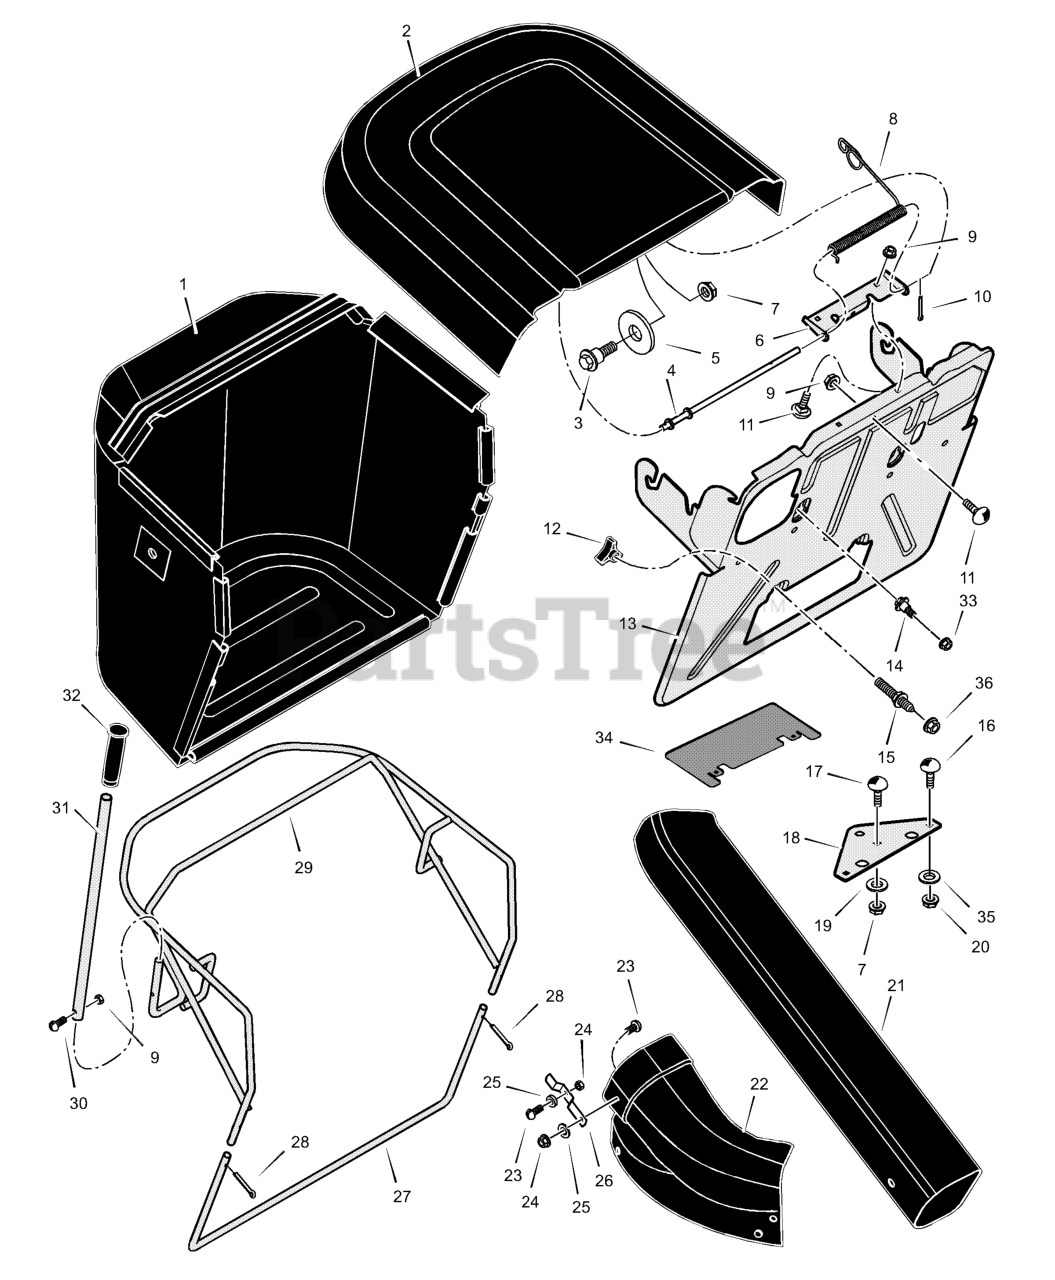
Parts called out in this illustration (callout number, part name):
1	Bag, Cloth
2	Cover, Bag (Red)
3	Bolt, Shoulder
4	Rod, Bag Lid
5	Washer
6	Hinge, Bag Top
7	Nut
8	Spring, Torsion
9	Nut
10	Pin, Cotter
11	Bolt, Carriage
12	Knob
13	Assembly, Bag Plate & Hanger
14	Bolt, Shoulder
15	Stud, Double End
16	Bolt, Carriage
17	Bolt, Carriage
18	Bracket, Hitch Extension
19	Washer
20	Nut
21	Tube, Connecting
22	Tube, Extension
24	Acorn Nut
25	Washer
26	Spring, Leaf
27	Tube, Bag Frame
28	Pin, Cotter
29	Frame, Bag
30	Bolt
31	Lever, Dump
32	Grip
33	Nut, Flange
34	Baffle, Bag Plate
35	Washer
36	Nut
